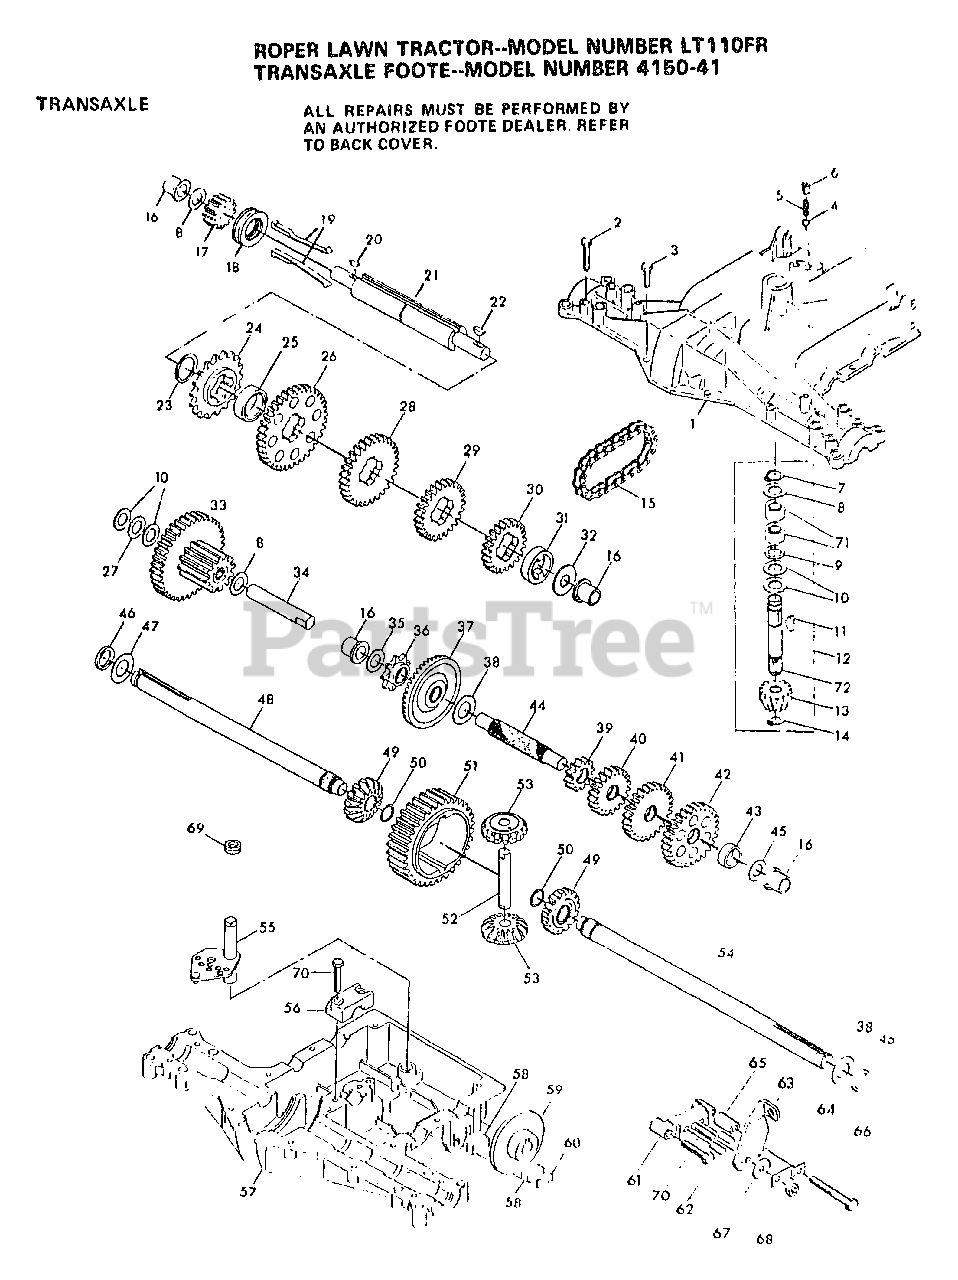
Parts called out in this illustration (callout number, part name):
1	HOUSING, UPPER
2	SCREW 1/4-20 X 1.31
3	SCREW 1/4-20 X .875
4	BALL DETENT
5	SPRING, DETENT
6	SCREW, SET
7	RING RETAINING
8	WASHER PLAIN
8	WASHER, PLAIN .632 X 1.00 X .026
8	WASHER, PLAIN .632 X 1.00 X .060
10	WASHER PLAIN
11	KEY WOODRUFF #9
12	ASSY KIT INPUT SHAFT
13	PINION, BEVEL, 14 TEETH
14	RING, RETAINING
15	CHAIN, 24 PITCHES
16	BEARING, FLANGE
17	GEAR SPUR, 14 TEETH
18	COLLAR CLUTCH
19	KEY, CLUTCH
20	KEY WOODRUFF #3
21	SHAFT, INTERMEDIATE
22	KEY, WOODRUFF, #61
23	RING, RETAINING
24	SPROCKET, 18T
26	GEAR, SPUR, 37 TEETH
27	SPACER .630 X 1.00 X .169
28	GEAR, SPUR 30T
29	GEAR, SPUR, 25 TEETH
32	WASHER, PLAIN .640 X 1.37 X .061
33	ASSY GEAR COMB 12&35 TEETH
34	SHAFT, IDLER
35	WASHER PLAIN
36	SPROCKET, 9T
37	GEAR, BEVEL, 42 TEETH
38	WASHER PLAIN
38	WASHER, PLAIN .758 X 1.25 X .031
39	GEAR, SPUR, 12 TEETH
40	GEAR, SPUR 20T
41	GEAR, SPUR, 25 TEETH
42	GEAR, SPUR, 31 TEETH
44	SHAFT, DRIVE
45	WASHER, PLAIN .632 X 1.00 X .060
47	WASHER, PLAIN .758 X 1.25 X .031
49	GEAR, MITER, 15 TEETH
50	RING, RETAINING
51	GEAR, SPUR, 32 TEETH
52	SHAFT, CROSS
53	GEAR, MITER, 15 TEETH
55	ASSY SHIFTER
56	CAP, SUPPORT
57	HOUSING, LOWER
58	PUCK, FRICTION
59	DISC, BRAKE
61	ASSY, JAW, BRAKE
62	PIN, DOWEL
63	LEVER, ACTUATING
64	BRKT, ANTI-ROTATION
66	SCREW 5/16-18 X 2.50
67	WASHER, PLAIN .321 X 1.00 X .055
68	LOCKNUT 5/16-24
70	SCREW TAPPING
